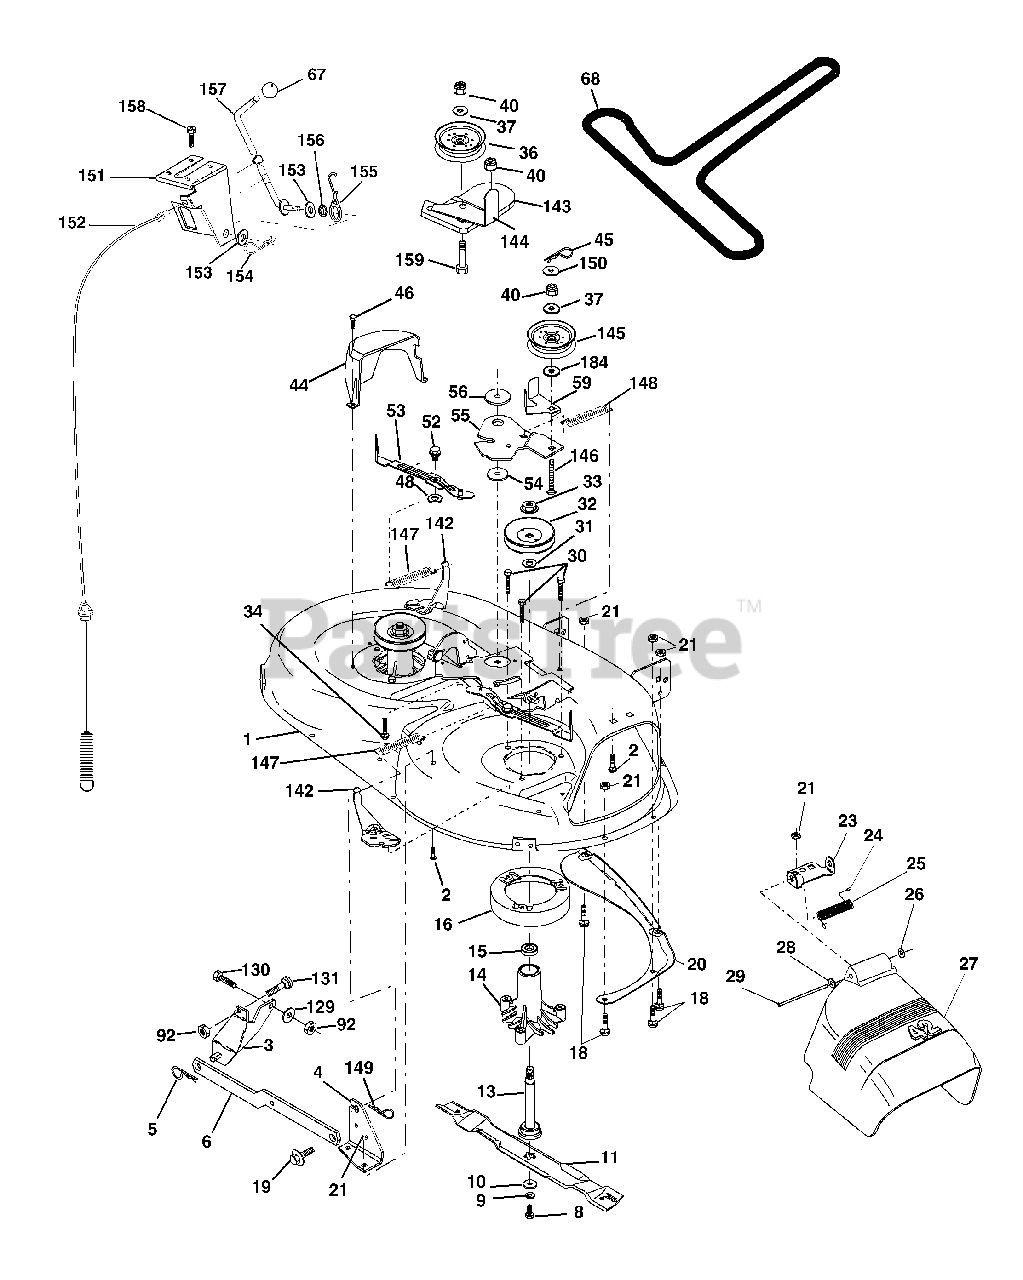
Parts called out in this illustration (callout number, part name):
1	Deck Asm MWR 42" weldment
2	Bolt Rdhd Sqnk 5/16-18unc X3/4
3	Bracket Asm Fr Sway Bar 38/42
4	Bracket Asm Deck 42"sway Bar
5	Retainer Spring
6	Deck Sway Bar
8	Bolt 3/8 - 24 X 1.25 Gr 8
9	Washer Lock Hvy 3/8
10	Washer Hard Blade Mower Vented
11	Blade Mower 42"
11	Blade, 42" Mulching Premium (For
11	Blade, 42" Hi-Lift
13	Shaft Asm W/lower Bearing
14	Housing Mandrel Vented
15	Bearing Ball Mandrel
16	Stripper Mower
18	Bolt Rdhd Sqnk 5/16-18 X 5/8
19	Bolt Shoulder
20	Baffle Vortex 42
21	Nut Crownlock 5/16-18 UNC
23	Bracket Deflector Mower 42"
24	Cap Sleeve 80x 112 Blk Mower
25	Spring Torsion Deflector 2 52
26	Nut Push Phos & Oil
27	Shield Deflector Mower 42" Blk
28	Washer 11/32 X 5/8 X 16 Ga
29	Rod Hinge 42" 6 75 Wlg
30	Screw Thd Rolling
31	Washer Spacer Mower Vented
32	Pulley Mandrel 42"
33	Nut Toplock Flng
34	Bolt Rdhd 3/8-16unc x 1-3/4 Gr5
36	Pulley Idler Flat
37	Washer 13/32 X 13/16 X 16
40	Nut Crownlock 3/8-16 UNC
44	Guard Mandrel LH Black
45	Spring Retainer 1" Zinc/cad
46	Screw Hex Thd Cut 1/4-20 x 5/8 T
48	Washer Hardened Smaller
52	Bolt Shoulder 5/16-18 Unc Blkz
53	Arm Asm Pad Brake
54	Washer Hardened
55	Arm Idler 42" mower LT/YT
56	Spacer Retainer Mower
59	Guard TUV Idler
67	Knob Rd 3/8-16 Plstc Thds Blk
68	V-Belt Mower 42"
92	Nut 3/8-16 Unc
129	Washer 13/32 x 13/16 x 12 Ga.
130	Bolt 3/8-16 x 1 Gr.5
131	Bolt 3/8-16 x 1
142	Arm Spring Brake Mower
143	Bracket Arm Idler 42"
144	Keeper Belt 42" Clutch
145	Pulley Idler Flat
146	Bolt Carriage Idler
147	Spring Extension
148	Spring Return Idler
149	Retainer Spring Yellow
150	Washer 9/32 x 3/4 x 16 Ga.
151	Bracket Clutch Cable
152	Clutch Cable 42"
153	Washer Flat 3/8" Type B
154	Spring Retainer
155	Spring Retention Lvr Cltch Cab
156	Spacer Clutch Cable
157	Rod Clutch Cable 3/8"
158	Screw Hex Thd Cut 1/4-20 x 1/2
159	Bolt Rdhd Sqn 3/8-16 Unc x 1-3/4
184	Washer 13/32 x 7/8 x 10 Ga.
